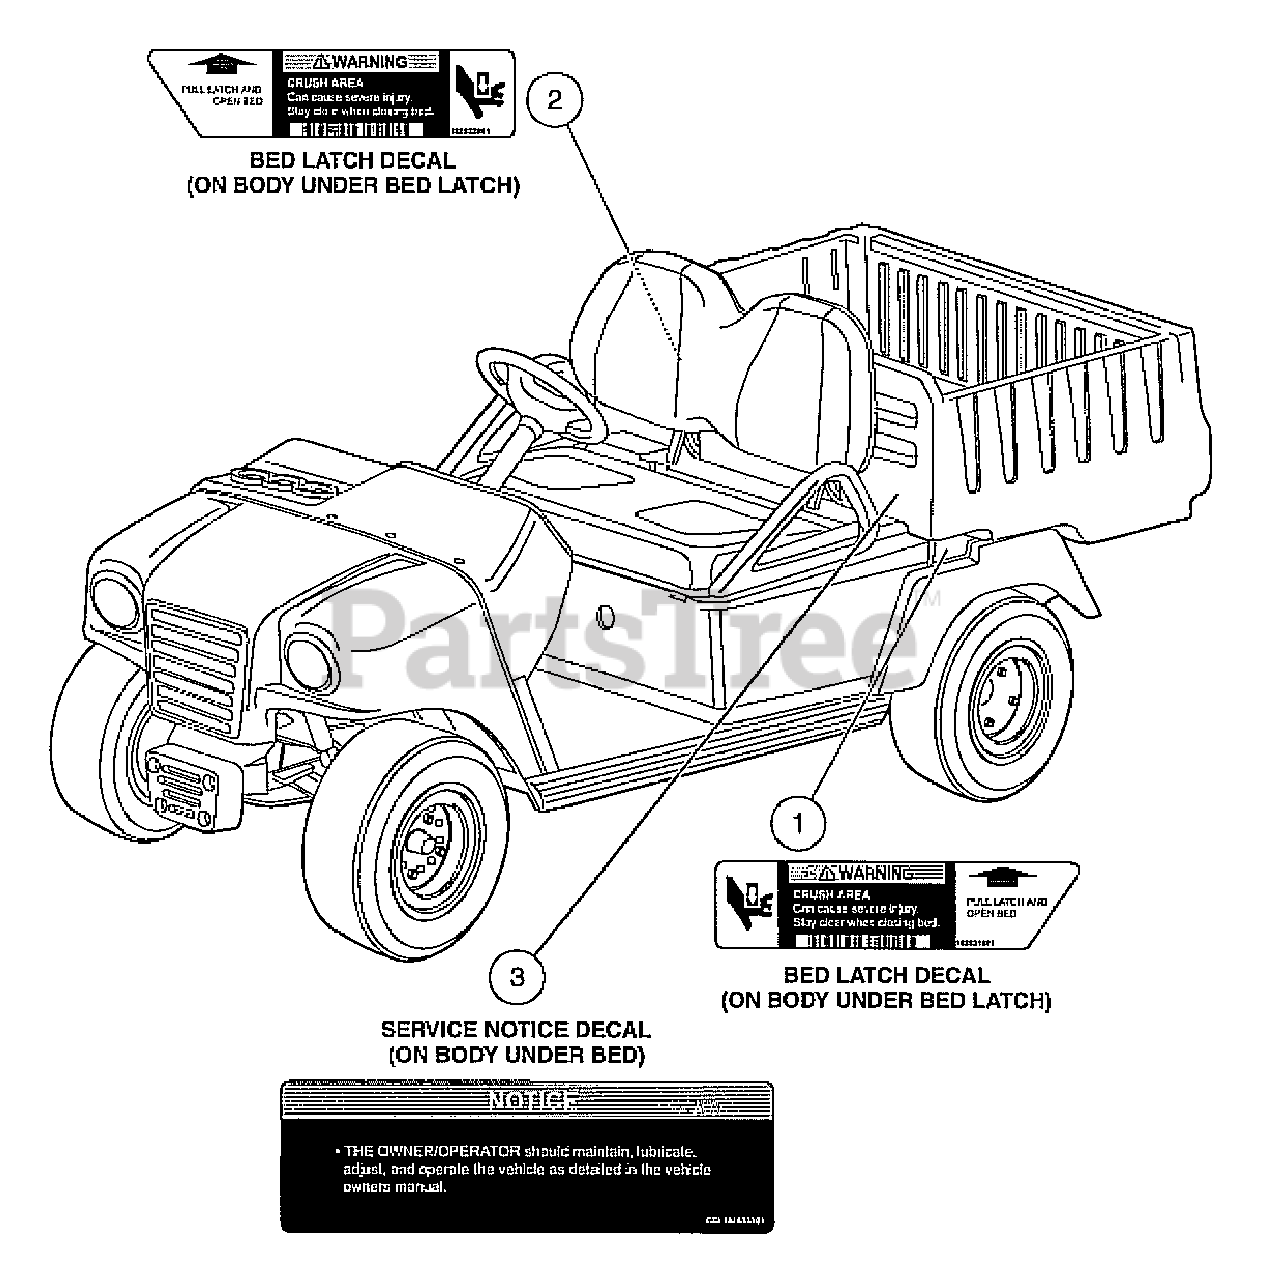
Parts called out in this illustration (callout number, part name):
1	Decal, Crush Warning, Driver Side
2	Decal, Crush Warning, Passenger-Side
3	Decal, Owner Notice
